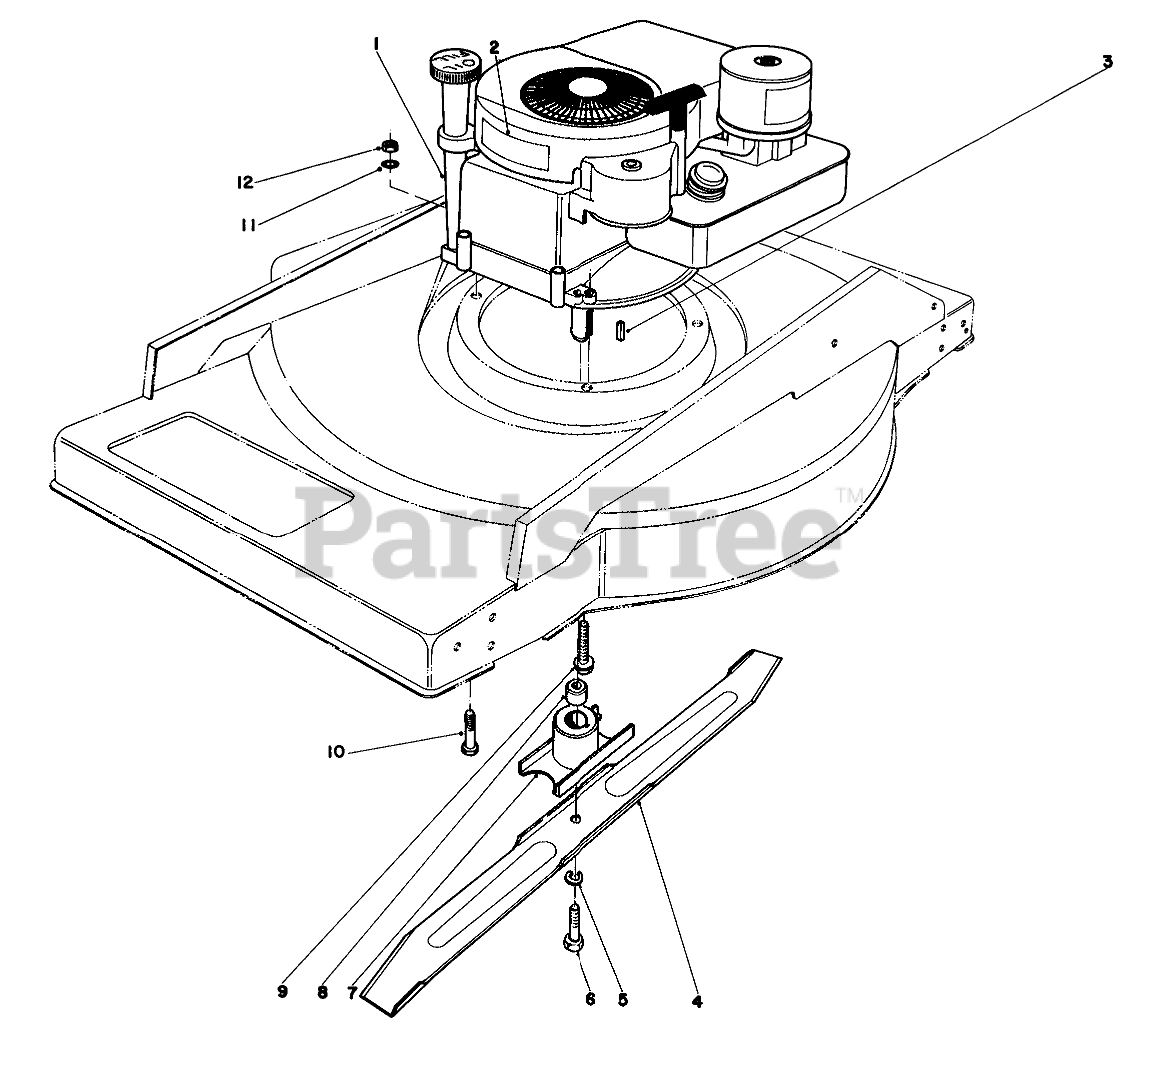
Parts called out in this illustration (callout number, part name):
1	Engine
2	Decal
3	KEY-SQUARE
4	Blade
5	WASHER-LOCK
6	BLADE SCREW
7	BLADE RETAINER WA
8	SPACER,BLADE RETAINER
9	SCREW-HWHTF
10	SCREW-HH
11	WASHER-FLAT
12	NUT-LOCK, CONE
